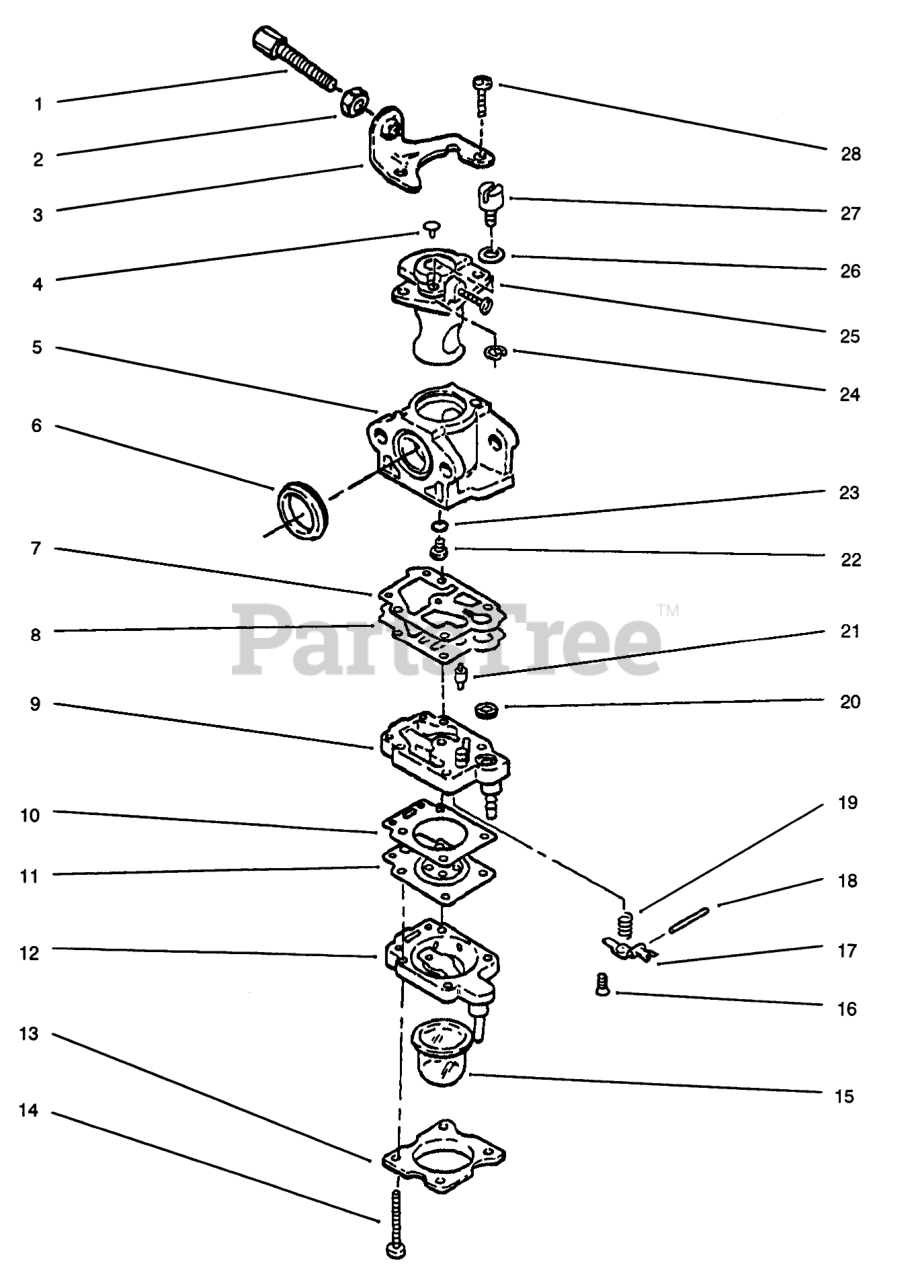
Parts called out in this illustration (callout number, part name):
1	ADJUSTING SCREW
2	LOCKNUT
3	BRACKET
5	Body-Carburetor (Ref.)
6	RUBBER CARB GASKET
7	DIAPHRAM GASKET
8	DIAPHRAGM
9	Body Ass-y-Fuel Pump (Incl. Ref. #20)
10	DIAPHRAGM GASKET
11	DIAPHRAGM
12	Body-Primer
13	Cover-Primer
14	Screw
15	PRIMER PUMP
16	Screw
17	Lever
19	Spring
20	SCREEN
21	NEEDLE VALVE
22	MAIN JET
23	MAIN JET O-RING
25	THROTTLE VALVE
26	WASHER
27	Holder-Wire
28	SCREW
